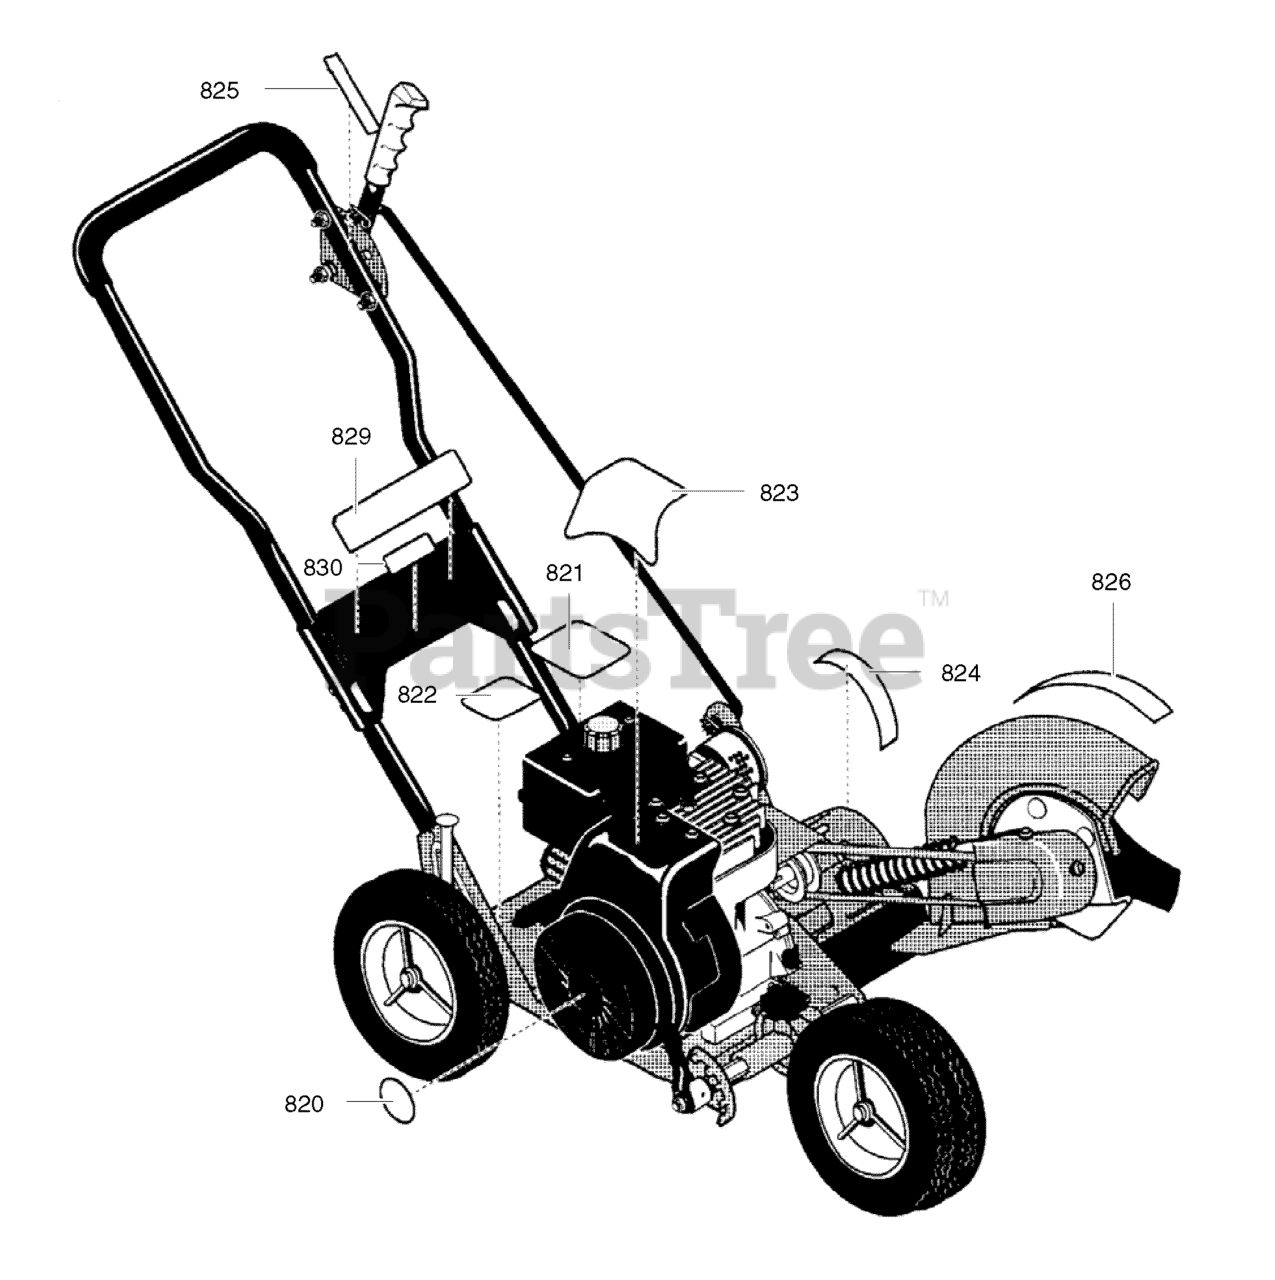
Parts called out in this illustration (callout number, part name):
820	DECAL, Recoil Cover
821	DECAL, Information Danger
822	REFERENCE ONLY
823	DECAL, Engine
824	DECAL, Angle Indicator
825	DECAL, Quadrant Selector
826	DECAL, Blade Guard
829	DECAL, Panel
830	DECAL, Husqvarna LE389
